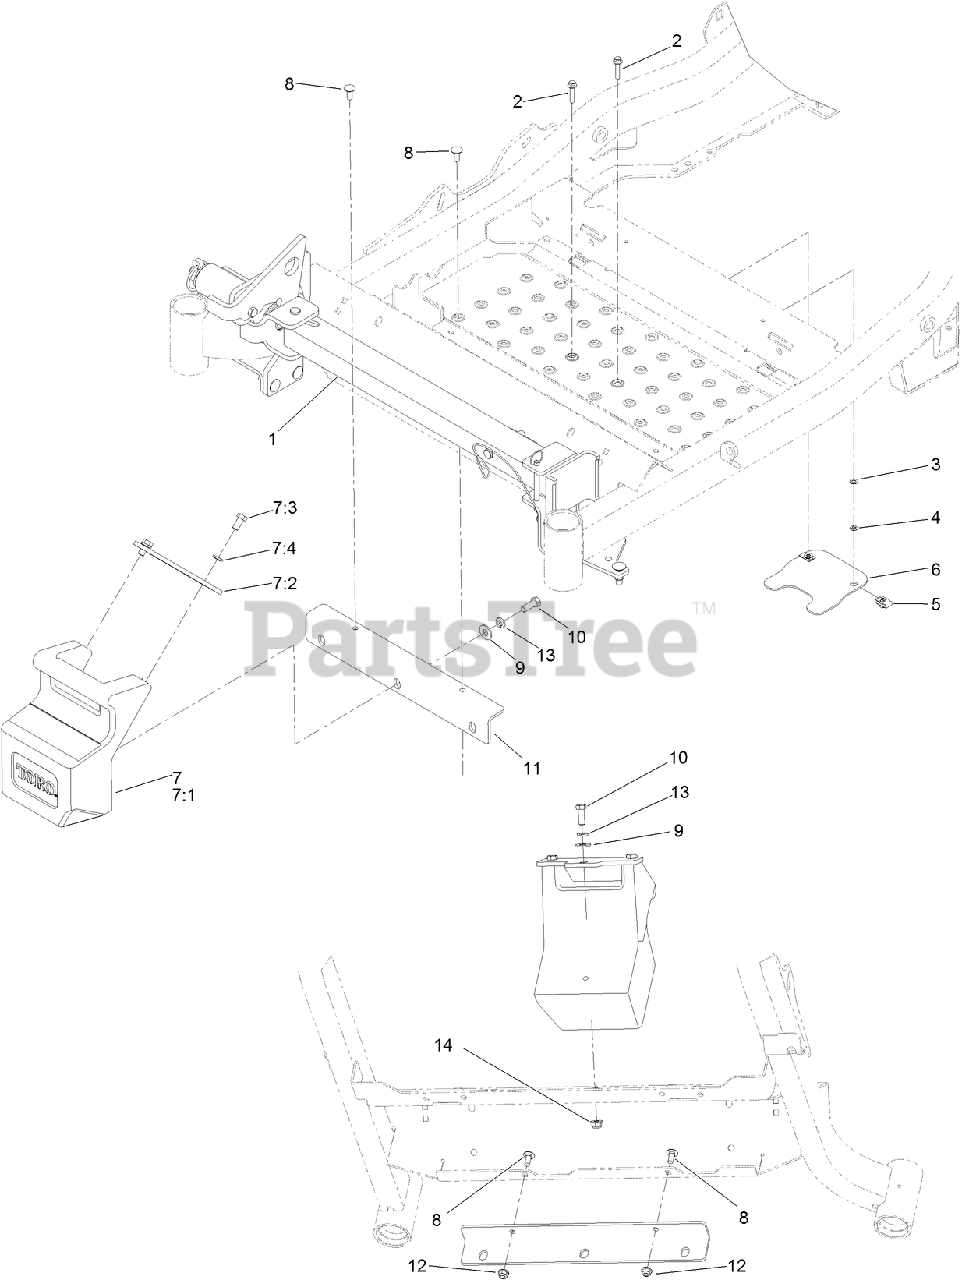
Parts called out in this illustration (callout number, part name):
1	Z STAND ASM
2	SCREW-HHF
3	WASHER-FLAT
4	NUT-RETAINER
6	ADAPTER-CAPTIVE
7	WEIGHT ASM
7:1	WEIGHT-43 LB
7:2	TAB-SUPPORT, WEIGHT
7:3	SCREW-HH
7:4	WASHER-LOCK
8	SCREW-CARR
9	WASHER-FLAT
10	SCREW-HH
11	BRACKET-MOUNT, WEIGHT
12	NUT-HF, NI
13	WASHER-LOCK
14	NUT-HF, NI
